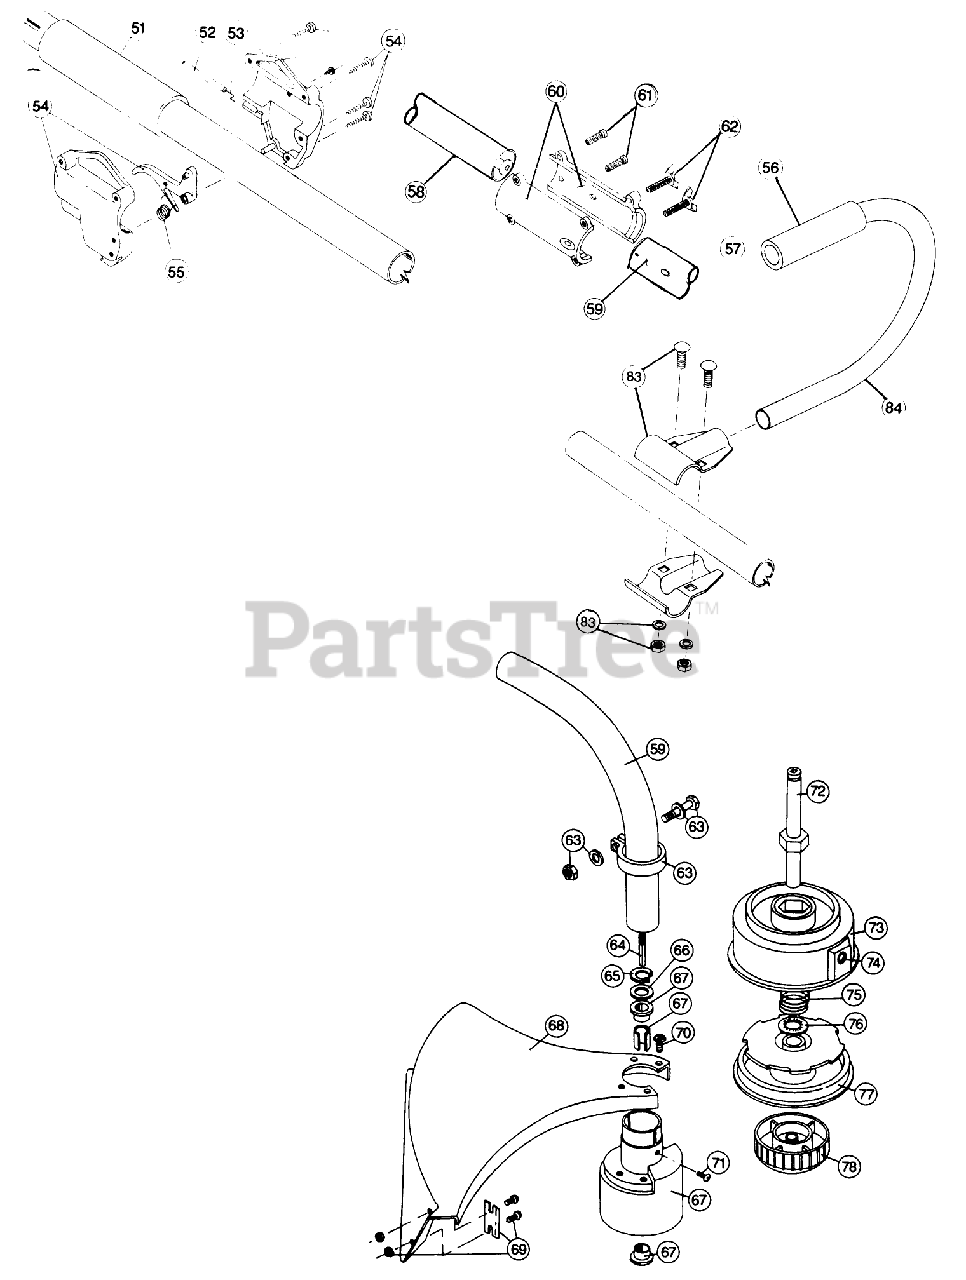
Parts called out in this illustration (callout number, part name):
53	THROTTLE CABLE WIRE
54	THROTTLE TRIGGER ASM
55	THROTTLE TRIGGER SPRING
56	HANDLE NITRILE GRIP
57	TUBE CLOSURE
62	ADJUSTMENT KNOB SET
65	RETAINING RING
66	WASHER
67	BUSHING HSG ASM
69	BLADE ASM
70	GUARD MOUNTING SCREW
71	ANTI-ROTATION SCREW
74	EYELET
75	SPRING
76	RETAINER WASHER
77	REEL - INNER
79	LOOP LINE
82	COMPLETE CUTTING HD ASM
85	STRAP SHOULDER ACC
